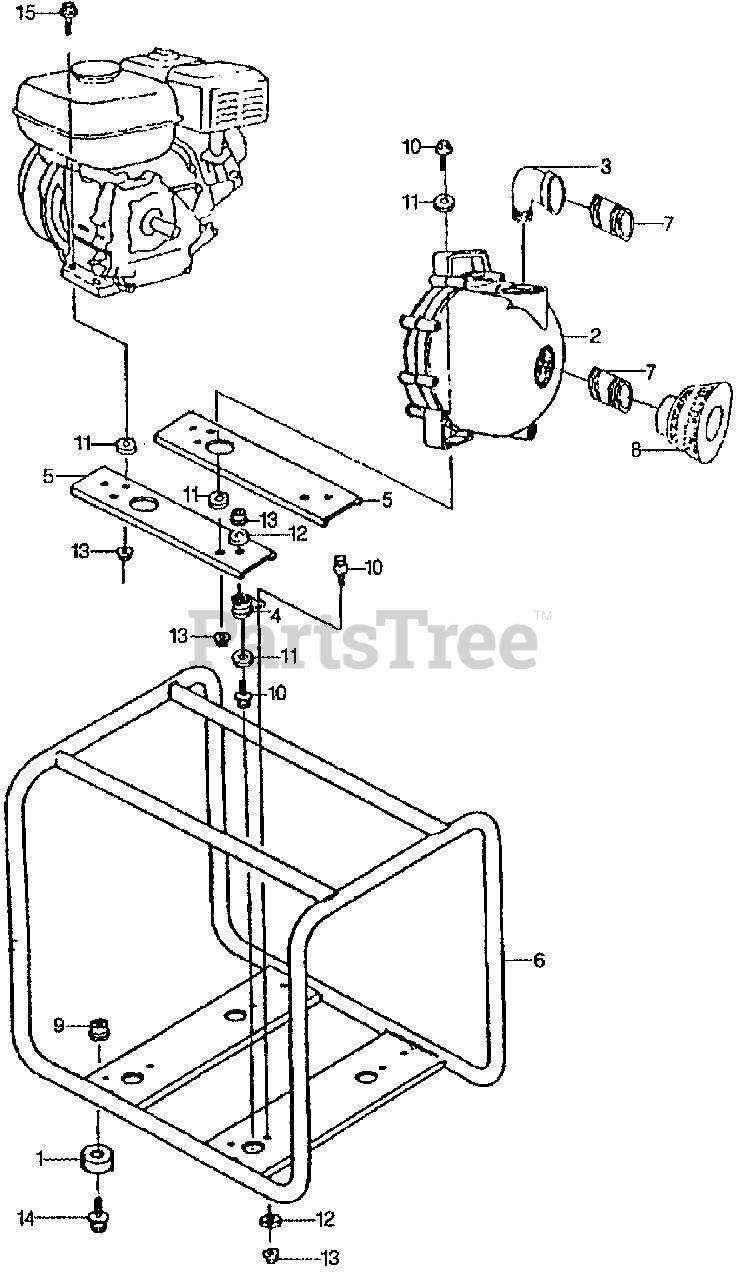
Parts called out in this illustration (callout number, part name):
1	RUBBER (LOWER)
2	PUMP ASSY. (TO ORDER COMPONENTS, SEE SECTION F-2.)
4	SPRING, MOUNT
5	STAY, MOUNT
7	COUPLING, HOSE
9	NUT, SELF-LOCK (8MM)
10	BOLT-WASHER (8X20)
11	WASHER, PLAIN (8MM)
12	WASHER, SPRING (8MM)
13	NUT, FLANGE (8MM)
14	BOLT, FLANGE (8X16)
15	BOLT, FLANGE (8X35)
